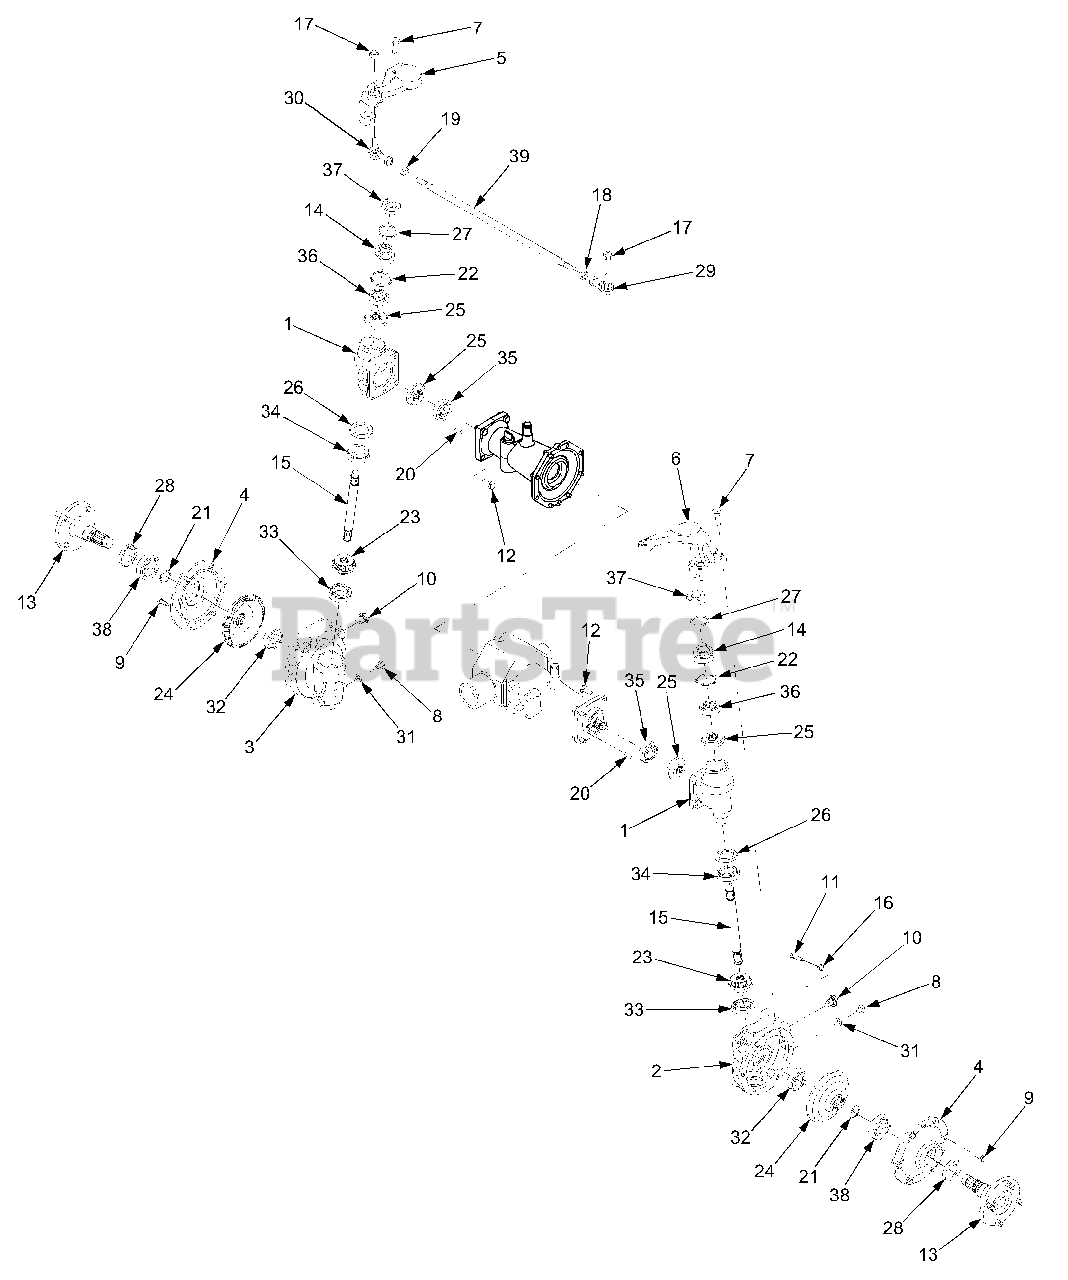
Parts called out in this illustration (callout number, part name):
1	Housing, Kingpin
2	Housing, Axle Drop, RH
3	Housing, Axle Drop, LH
4	Cover, Axle
5	Arm, Steering, LH
6	Arm, Steering, RH
7	Screw, Hex Cap, M10-1.5 x 35 GR8.8
8	Plug, Hex, 3/8-16 x .5
9	Screw, Hex Cap, M8-1.25 x 20 GR8.8
10	Plug, Screw, M14-1.5 x .827
11	Screw, Hex Cap, M8-1.25 x 30
12	Screw, Hex Cap, M10-1.5 x 25
13	Axle, Flange
14	Shaft, Stub
15	Shaft, Kingpin
16	Nut, Hex, M8-1.25
17	Nut, Hex Flange Lock, M12-1.75
18	Nut, Hex, M12-1.75 RH Thrd.
19	Nut, Hex, M12-1.75 LH Thrd
20	Pin, Dowel, 8mm x 20mm
21	Ring, Retaining
22	Ring, Retaining
23	Gear, Bevel, 13T
24	Gear, Bevel, 34T
25	Gear, Bevel, 14T
26	Seal, Oil, 38mm x 55mm x 7mm
27	O-Ring, 40mm x 3mm
28	Seal, Oil, 35mm x 55mm x 8mm
29	Ball Joint, 12-1.75 RH
30	Ball Joint, 12-1.75 LH
31	Washer, Flat, .39 x .75 x .062
32	Bearing, Ball
33	Bearing, Ball
34	Bearing, Tapered Roller w/ Race
35	Bearing, Ball
36	Bearing, Ball
37	Bearing, Ball
38	Bearing, Ball
39	Rod, Tie, M12-1.75
